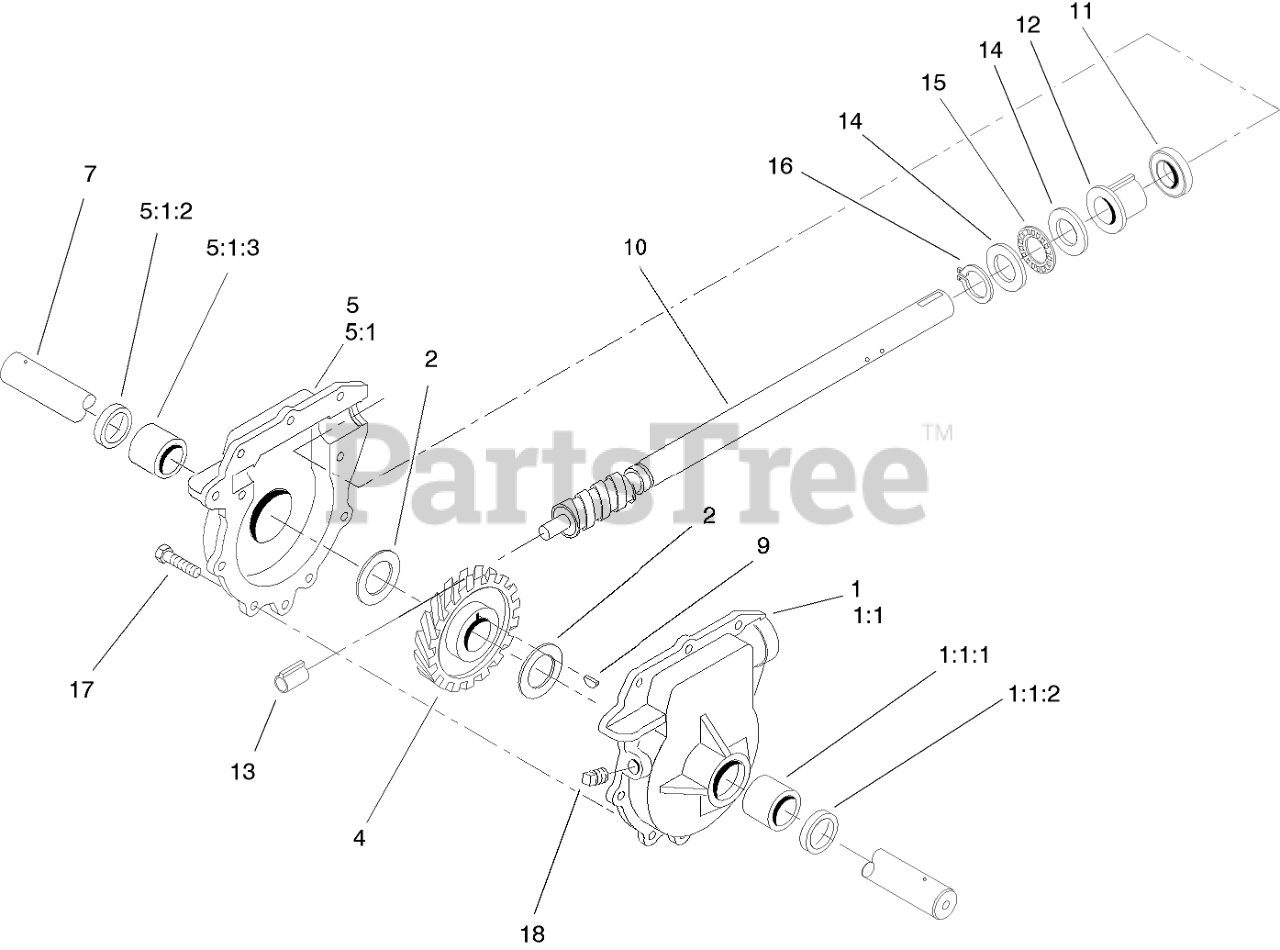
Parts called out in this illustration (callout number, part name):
1	LH AUGER GEARCASE ASM
1:1	Gearcase-Auger, LH
1:1:1	BUSHING
1:1:2	SEAL-OIL
2	WASHER-THRUST
4	GEAR-HELICAL
5	RH AUGER GEARCASE ASM
5:1	GEARCASE-AUGER, RH
5:1:2	SEAL-OIL
5:1:3	BUSHING
7	SHAFT-AUGER
9	KEY-WOODRUFF
10	SHAFT-IMPELLER
11	SEAL-OIL
12	BUSHING-INPUT
13	BUSHING-WORM
14	WASHER-THRUST
15	BEARING-THRUST
16	RING-RETAINING, Ext
17	SCREW-HWH
18	PLUG-PIPE, SQH
